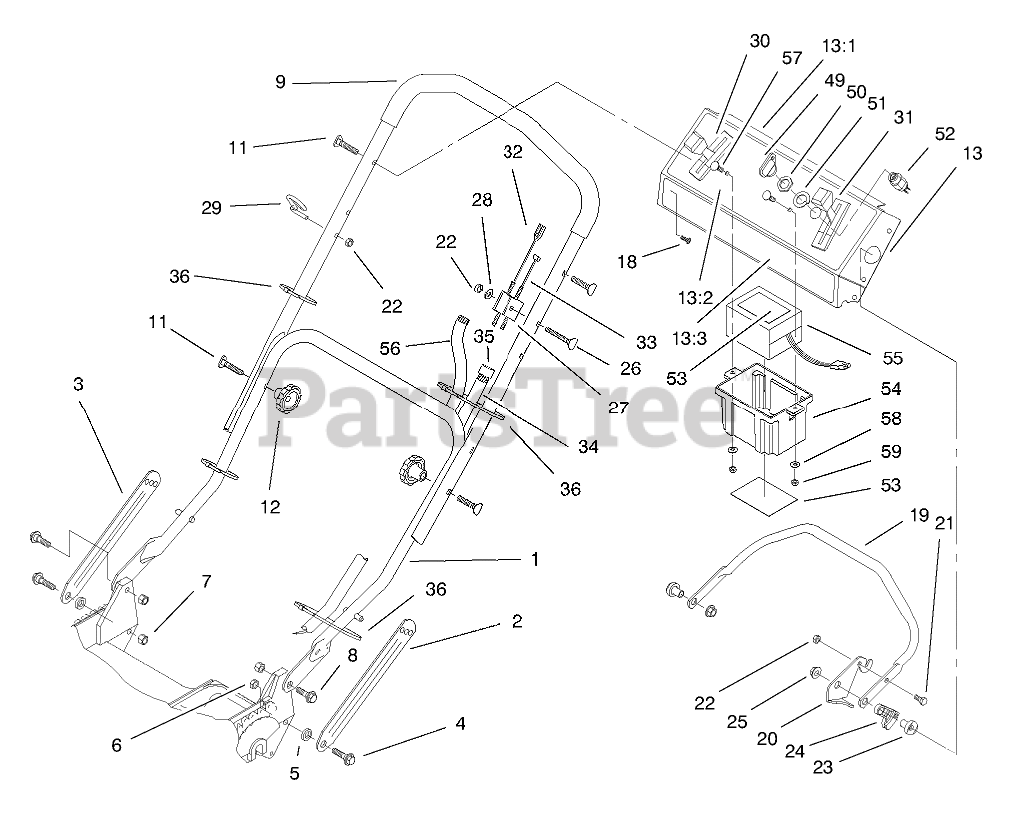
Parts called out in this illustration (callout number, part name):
1	ASM-Handle
2	Latch-Handle
3	Latch-Handle
4	SCREW-SHOULDER
5	SPACER
6	NUT-LOCK, NI
7	NUT-LOCK, NI
8	SCREW-SHOULDER
9	HANDLE - DIPPED
11	SCREW-HANDLE
13	ASM - PANEL W/DECALS
13:1	DECAL-PANEL, REAR
13:2	DECAL - INSTRUCTIONS
13:3	DECAL - PANEL
18	SCREW-TAP
19	Bar-Control
20	Lever-Control
21	SCREW-HH
22	NUT-LOCK, NI
23	SPACER-SUPPORT
24	LEVER-TRACTION
25	NUT-LOCK NI
26	SCREW-HANDLE
27	SUPPORT-CABLE
28	WASHER-FLAT
29	GUIDE-ROPE
30	CONTROL-SPEED, GROUND
31	CONTROL - THROTTLE
32	BRAKE CONTROL
33	CABLE-TRACTION
34	CONTROL CABLE COVER
35	FITTING-RING
36	TIE-CABLE
49	KEY-IGNITION
50	NUT-HH
51	WASHER-TOOTH, INTERNAL
52	STARTER SWITCH ASM
53	DECAL-BATTERY
54	COVER - BATTERY
55	BATTERY ASSEMBLY
56	WIRE HARNESS
57	SCREW-CARR
58	WASHER-FLAT
59	NUT-LOCK, NI
